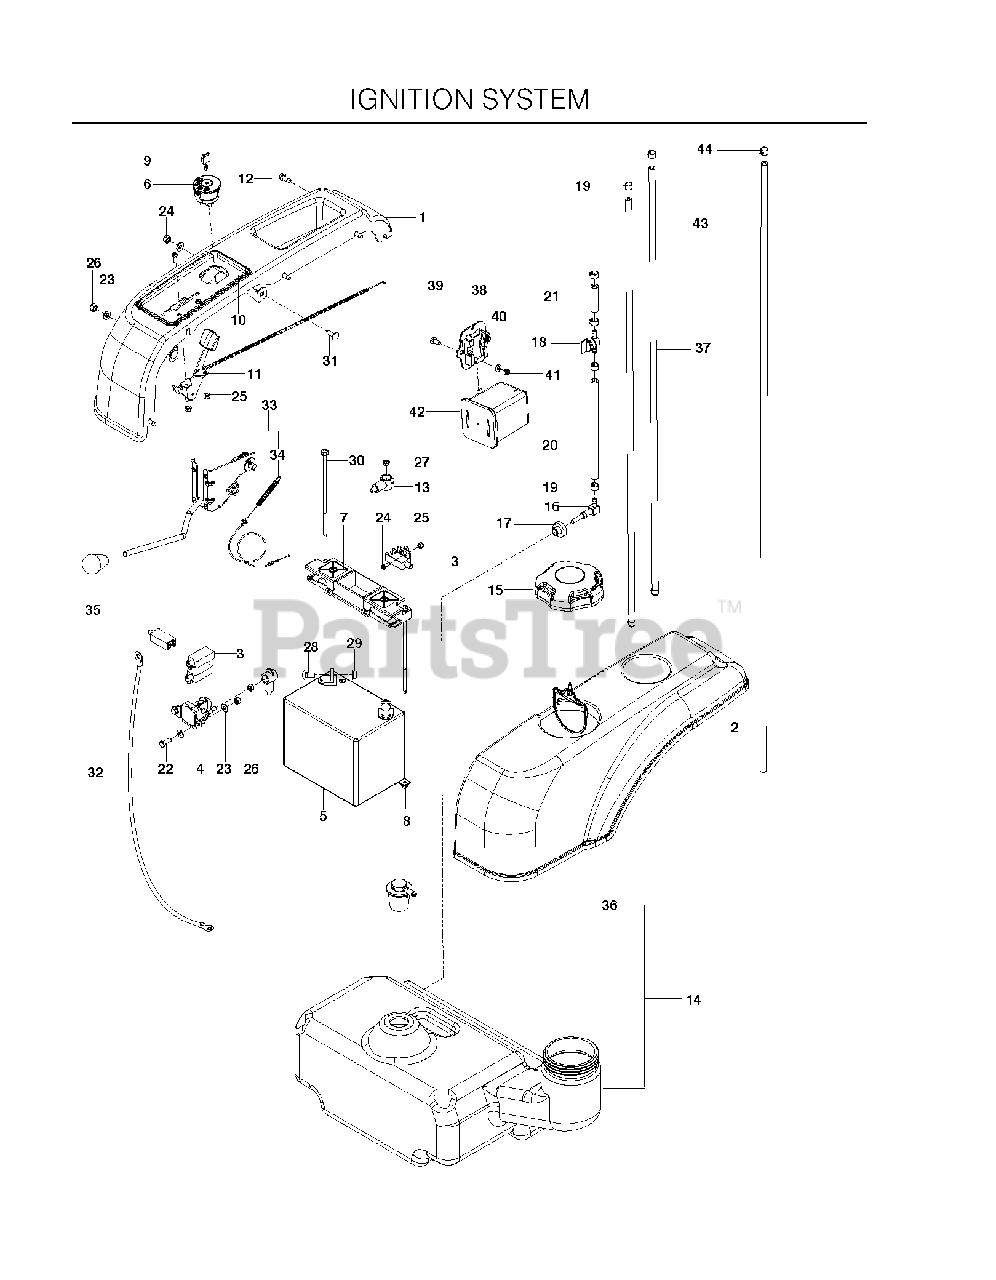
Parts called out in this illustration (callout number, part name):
1	FENDER RH
2	FENDER LH
3	SWITCH, INTERLOCK
4	SOLENOID
5	BATTERY, 12 V 330 AMP TBR
6	IGNITION SWITCH
7	BATTERY HOLD DOWN
8	PUSH NUT-NYLON
9	KEY
10	MOUNT, CONTROLS, BLK
11	THROTTLE CABLE
12	SCREW 1/4 X 5/8
13	TERMINAL COVER-SM
15	CAP, FUEL
16	ELBOW W/FILTER
17	TANK FITTING
18	FUEL VALVE
19	HOSE CLAMP
20	HOSE 1/4 X 8
21	HOSE 1/4 X 2"
22	HCS 1/4C X 3/4 HCS
23	WASHER 1/4 SAE
24	SCREW #10-24 X 5/8
25	NUT 10-24 NYLOC
26	NUT 1/4-20 NYLOC
27	JAM NUT 1/4C
28	BOLT 5/16C X 3/4" CARRIAGE
29	5/16-18 NYLOC FLANGE NUT
30	BOLT - 1/4-20 X 7.5
31	RHSNB 1/4C X 3/4
32	BATTERY CABLE, NEGATIVE
33	ASM, CLUTCH ENGAGE W/CABLE
34	CABLE.CLUTCH.38".SERVICE
35	KNOB - SHIFT
36	CANNISTER, CARBON
37	FUEL LINE 24"
38	BRACKET, CANISTER
39	HCS 5/16-18 X 5/8 GR 5 ZD
40	FLAT WASHER 5/16 SAE
41	5/16-18 THIN PROF NY
42	CANNISTER, CARBON
43	HOSE, FUEL 3/16" X 42"
44	CLAMP, HOSE
